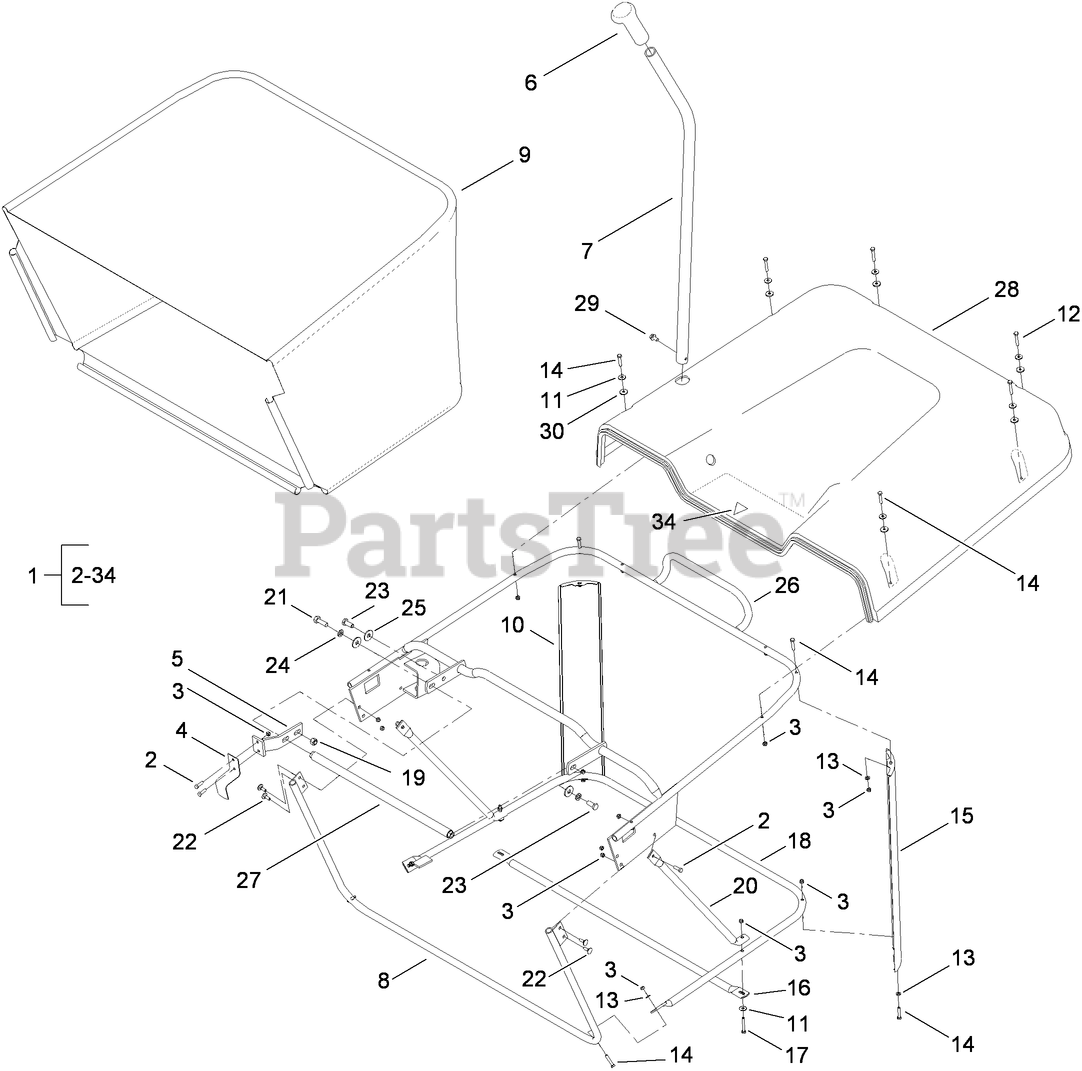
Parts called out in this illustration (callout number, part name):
1	COLLECTOR ASM
2	SCREW-HH
3	NUT-LOCK
4	SPRING-COLL, INTERLOCK SWITCH
5	Bracket-Spring
6	GRIP-HANDLE
7	LEVER-DUMP
8	FRONT FRAME ASM
9	BAG-GRASS
10	SUPPORT-CORNER, RIGHT
11	WASHER-FLAT
13	WASHER
14	SCREW-HEX
15	SUPPORT-CORNER, LEFT
16	BRACE-CONNECTING
17	SCREW-HEX
18	BOTTOM FRAME ASM
19	NUT-LOCK, NI
21	SCREW-HH
22	BOLT-CARRIAGE
23	SCREW-HH
24	WASHER-LOCK
25	WASHER-PLAIN
26	TOP FRAME ASM
27	HANDLE-LIFT
28	Cover-Collector
30	WASHER-RUBBER
34	DECAL-BAG TO FRAME
